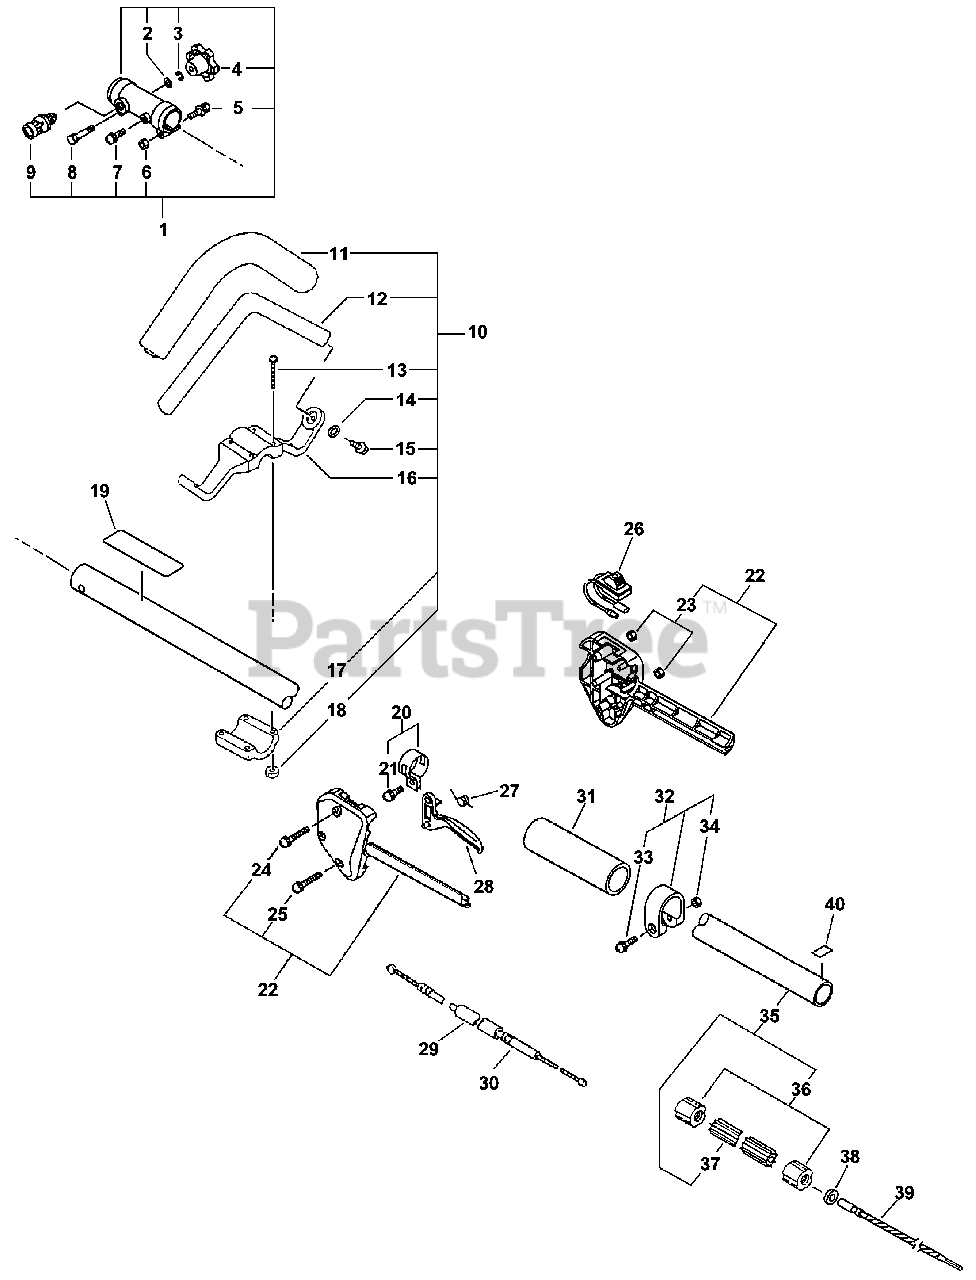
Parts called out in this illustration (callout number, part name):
1	COUPLER ASSY
2	WASHER, FLAT 5.5×10×0.8
3	WASHER, SPRING 5
4	KNOB
5	BOLT 5×30
6	NUT M5
7	SCREW 5×12
8	BOLT 5×40
9	LATCH ASSY
10	HANDLE ASSY, FRONT
11	GRIP, HANDLE
12	HANDLE, SUPPORT
13	BOLT 5×40
14	WASHER, FLAT 5.5×10×0.8
16	BRACKET, HANDLE
17	BRACKET, HANDLE - LOWER
18	NUT M5
19	LABEL, CAUTION
20	CLAMP KIT
21	SCREW 5×14
22	HANDLE KIT, CONTROL
23	NUT M5
24	SCREW 5×35
25	SCREW 5×25
26	SWITCH, ON-OFF
27	SPRING, TORSION
28	TRIGGER, THROTTLE
29	TUBE, FLEXIBLE
30	CABLE, THROTTLE
31	GRIP, HANDLE
32	CLAMP KIT
33	SCREW 5×28
34	NUT M5
35	MAIN PIPE ASSY
37	LINER - FLEXIBLE
39	DRIVESHAFT - FLEXIBLE
40	LABEL - ALIGNMENT
